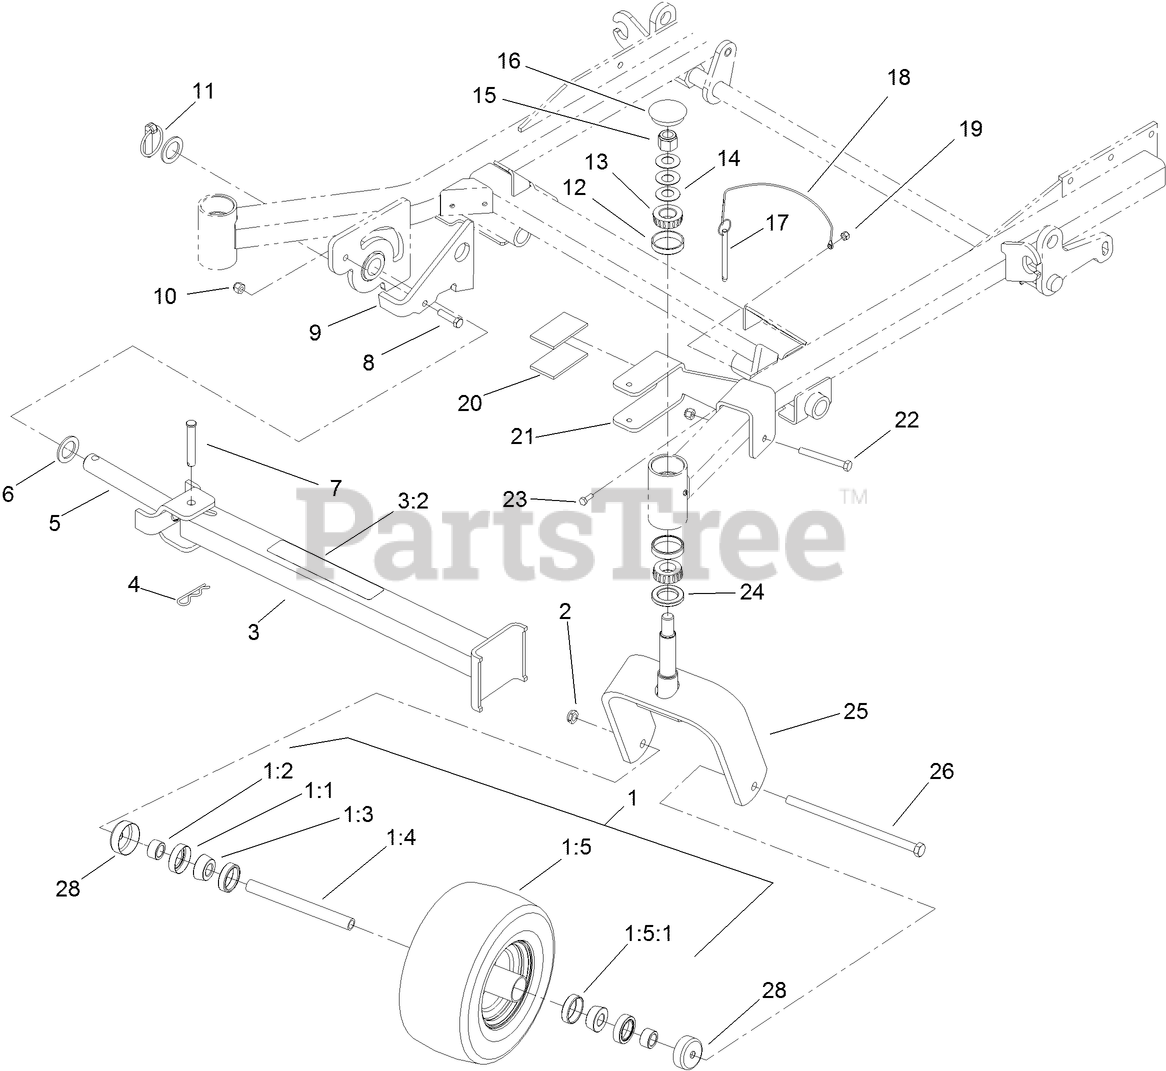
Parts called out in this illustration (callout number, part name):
1	WHEEL AND TIRE ASM
1:1	BEARING-CONE, TAPER
1:2	SEAL-CASTER
1:3	SPACER-NUT
1:4	AXLE-CASTER
1:5	WHEEL AND TIRE ASM
1:5:1	BEARING-CUP
2	NUT-LOCK, NI
3	Leg ASM
3:2	DECAL-Z STAND
4	PIN-HAIR
5	PIN-PIVOT
6	WASHER-THRUST
7	PIN-CLEVIS
8	SCREW-HH
9	BRACKET-LATCH
10	NUT-LOCK, NI
11	PIN-LYNCH
12	BEARING-CUP, TAPERED
13	BEARING-CONE, TAPERED
14	WASHER-BELLVILLE
15	NUT-LOCK, NI
16	CAP-GREASE
17	PIN-HITCH, COTTERLESS
18	LANYARD-NYLON
19	NUT-LOCK, NI
20	Cushion-Rubber
21	BRACKET-CRADLE
22	SCREW-HH
23	SCREW-HH
24	SEAL-GREASE
25	CASTER-FORK
26	Screw-HH
28	GUARD-SEAL
